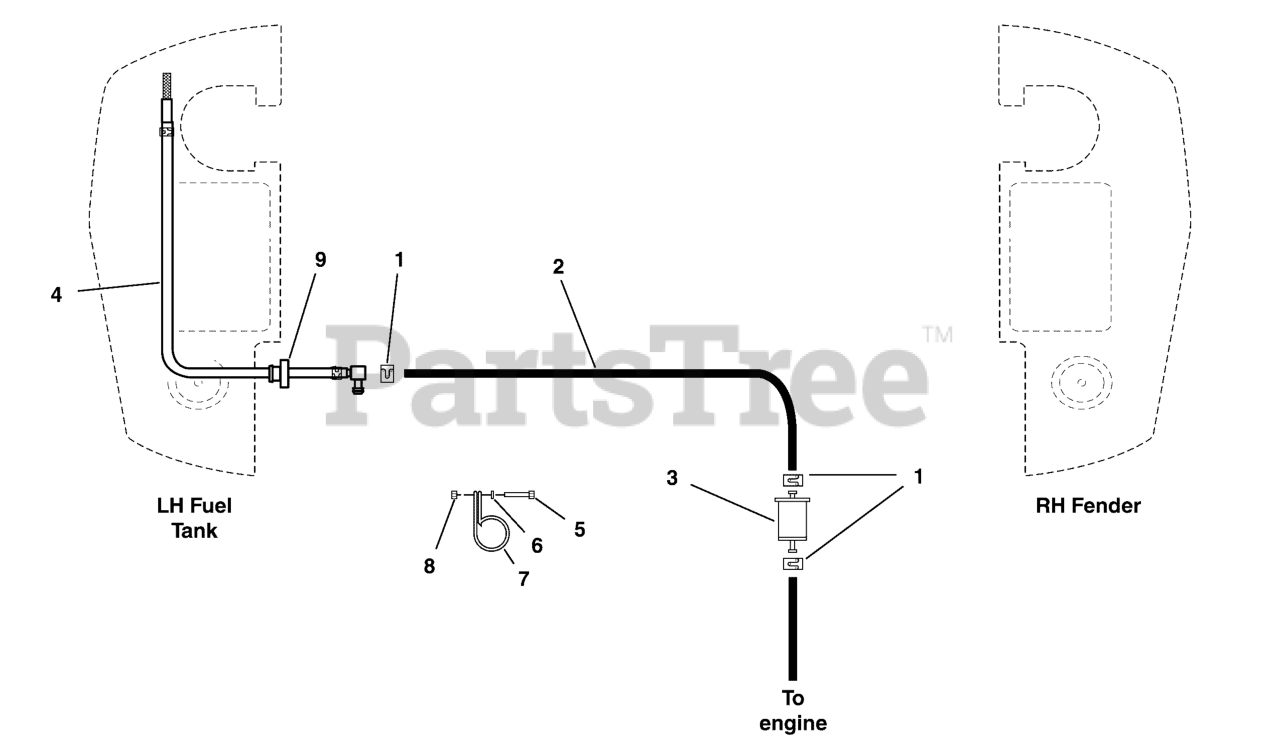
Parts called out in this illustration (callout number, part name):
1	CLAMP, Hose
2	Refer to: Engine & PTO Group
3	FUEL FILTER (SV)
4	PICKUP TUBE ASM, FUEL TANK, 22"
5	BOLT, 1/4"-20 X 3/4" GD5 YZ
6	WASHER, 1/4 SAE
7	CLAMP, VINYL INSULATED, 1.00
8	NUT, 1/4-20 Hex Nylock Flange
9	BUSHING-FUEL TANK RED RUBBER
